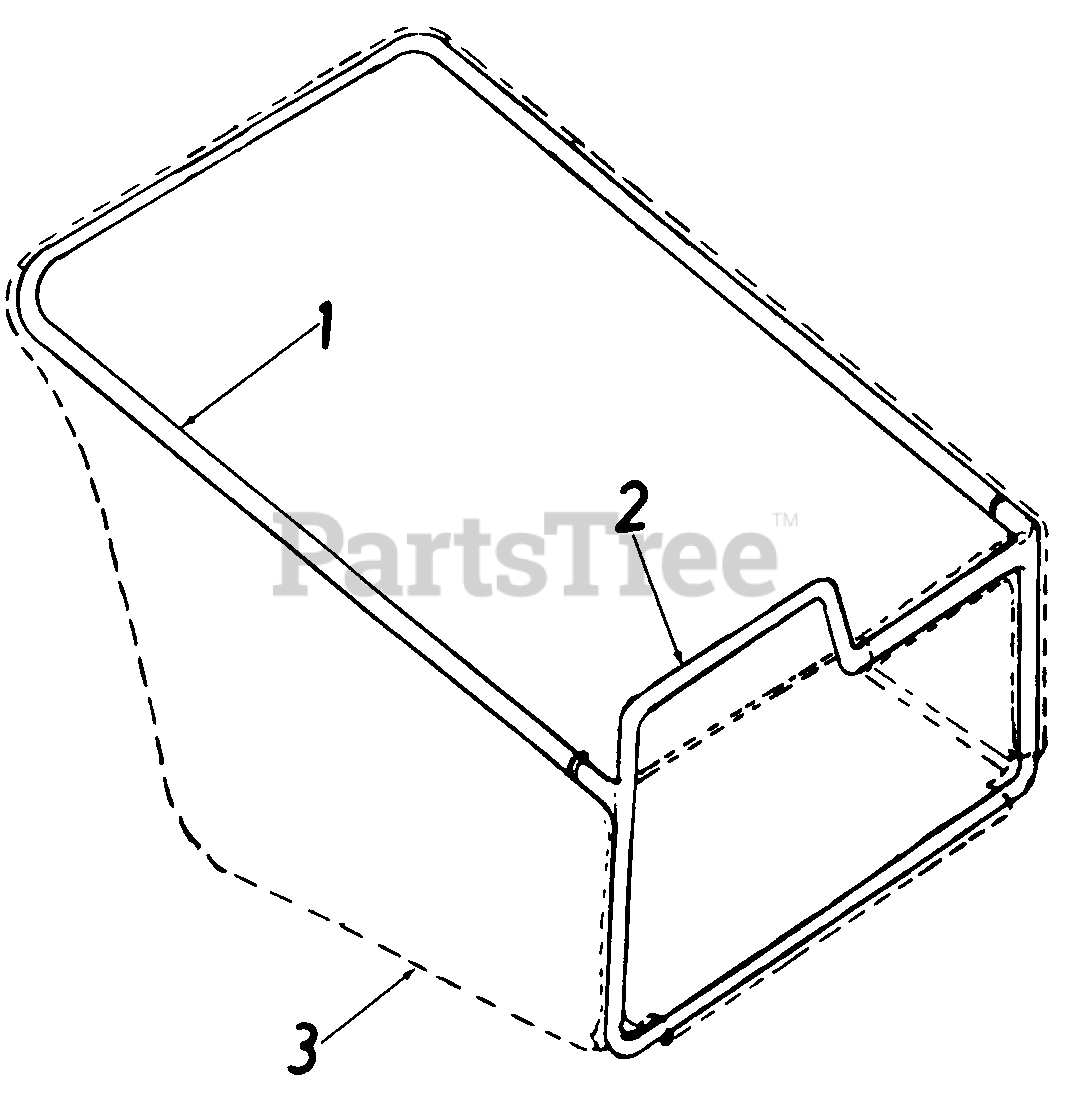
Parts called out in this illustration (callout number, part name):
1	Grass Catcher Upper Frame
2	Grass Catcher Lower Frame Ass'y.
3	Grass Bag
